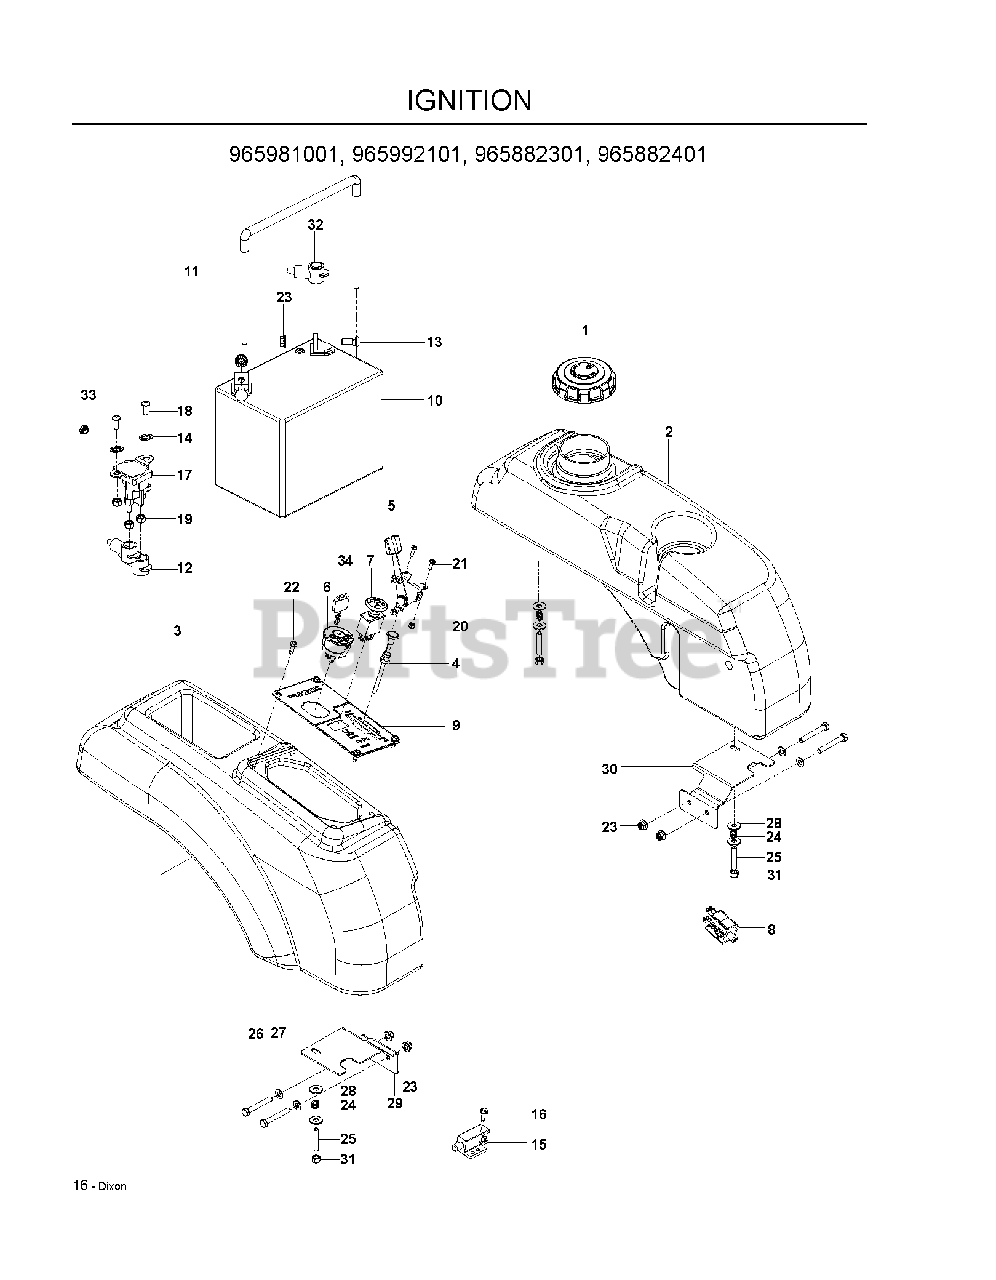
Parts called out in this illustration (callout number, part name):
1	FUEL CAP, GENERIC
2	FUEL TANK ASM LH
3	FENDER RH
4	PUSH/PULL CHOKE CABLE
5	CABLE THROTTLE
6	IGNITION SWITCH
7	SWITCH, BLADE
8	SWITCH, BRAKE 3P
9	DECAL, CONTROL PANEL SPDZTR
10	BATTERY, 12 V 330 AMP TBR
11	BATTERY TIE DOWN ASSEMBLY
12	TERMINAL COVER-SM
13	BOLT 5/16C X 3/4" CARRIAGE
14	WASHER 1/4 INT TOOTH
15	SWITCH, INTERLOCK
16	SCREW #10 X 1/2 SELF TAPPING
17	SOLENOID
18	SCR 1/4-20 X 5/8 BTN SKT HD ZD
19	NUT 1/4-20 NYLOC
20	NUT 10-24 NYLOC
21	SCREW #10-24 X 5/8
22	SCREW 1/4 X 5/8
23	5/16-18 NYLOC FLANGE NUT
25	STUD, 5/16C
26	CAPSCREW
27	FLAT WASHER 5/16 SAE
28	WASHER 5/16 FLAT
29	SUPPORT, TANK LT BLK
30	SUPPORT, TANK, RT BLK
31	NUT 5/16 NYLOC
32	INSULATOR
33	JAM NUT 1/4C
34	KEY
